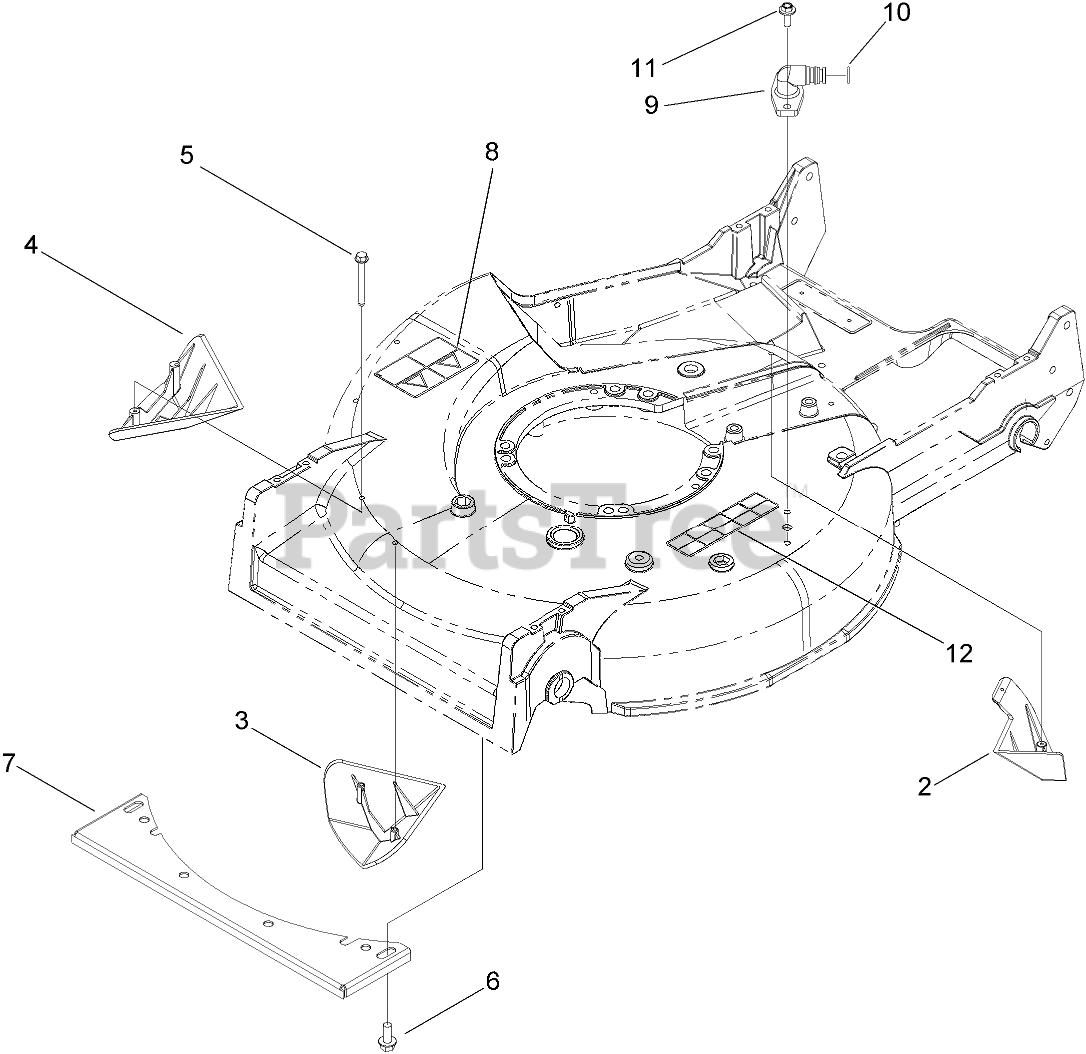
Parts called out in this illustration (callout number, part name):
2	KICKER-REAR
3	KICKER-FRONT
4	KICKER-RH
5	SCREW-PPH
6	SCREW-HWHTF
8	DECAL-DANGER
9	FITTING-WASHOUT
10	O-RING
11	SCREW-HWH
12	DECAL-DANGER
